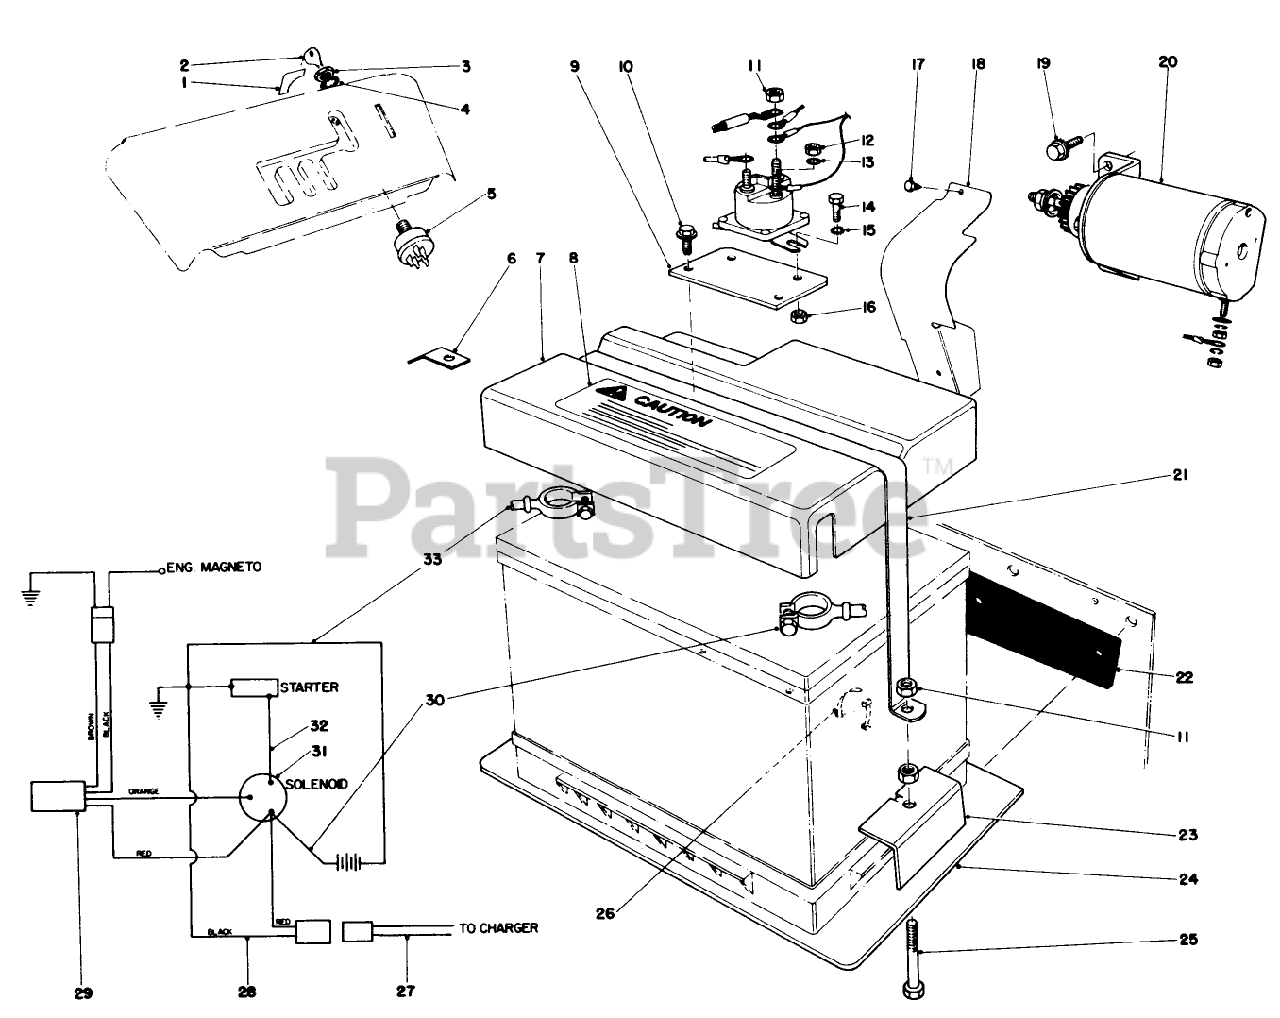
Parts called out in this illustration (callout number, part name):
3	NUT-HH
4	WASHER-LOCK
5	SWITCH-STARTER
8	Decal-Caution
10	SCREW-HWH
11	NUT-HEX
12	NUT-HEX
13	WASHER-LOCK, INT
14	SCREW-HH
15	SCREW-HH
16	NUT-LOCK, NI
18	BRIGGS 280265
19	5/16-18X3/4 HX HD SEM
20	Starter Motor Pinion Assy.
25	SCREW-HH
26	TIE-CABLE
27	MALE WIRE ASM
30	BATT-SOLENOID CABLE
31	SOLENOID
